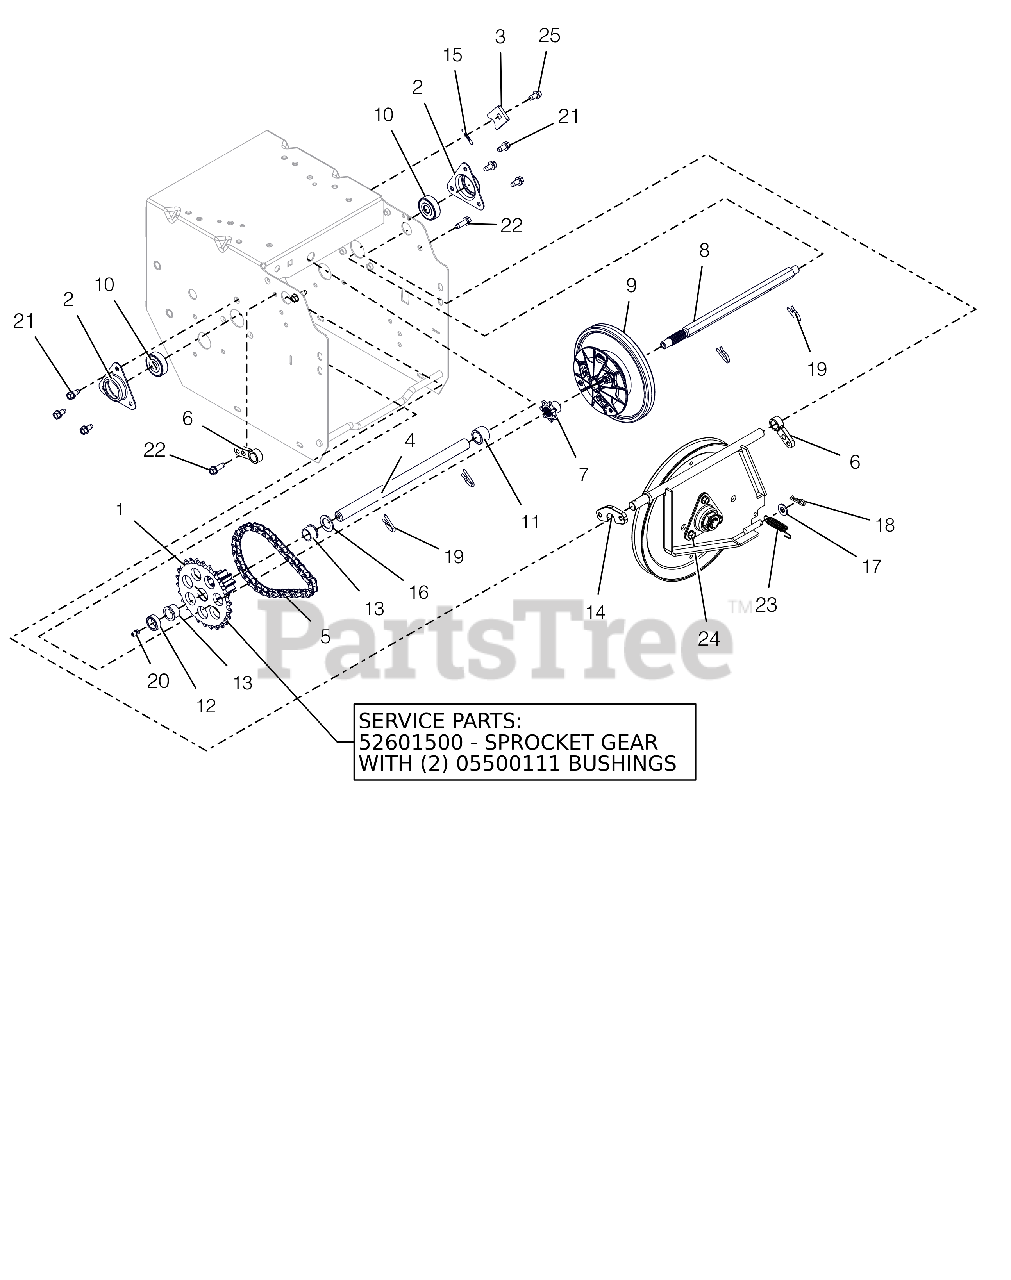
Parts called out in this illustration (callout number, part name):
1	PINION & SPROCKET
1	PINION & SPROCKET W/BUSHINGS
1	BSHG-FLG .625X.750X.500X.875
2	FLANGE, BEARING
3	TAB, ANTI ROTATION
4	SHAFT, PINION
5	CHAIN - #41, 32 PITCHES
6	SUPPORT BUSHING, SWING GATE
7	SPROCKET, PINION 7T W/SPLINE
8	SHAFT, HEX W/SPLINE
9	DISC, FRICTION DRIVE-ASSEMBLY
10	BRG-BALL .437X1.375X.437
11	SPACER, .635X.880X.611
12	BSHG-SLV, .635X.880X.305
13	BSHG-FLG .625X.750X.500X.875
14	SPACER, SWING GATE
15	@PIN-GRV .125X1.00 TP E ALLOY
16	WSHR-FL-STL .630X1.005X.062 YZ
17	@WSHR-FL-STL.344X.688X.065YWZC
18	PIN-HAIR INT .08X.18X1.18 YWZC
19	PIN, SPRING CLIP
20	ZERK,FITTING .25X.125 DRIVE IN
21	SCR-TAP .25-20X.50 HWH TR YWZ
22	SCR-TAP-PM .25-20X.75 TR YWZ
23	SPRING, EXT. .043X.438X1.64
24	PLATE, SWING - ASSEMBLY
25	SCR-TAP .25-20X.50 HWH TR YWZ
